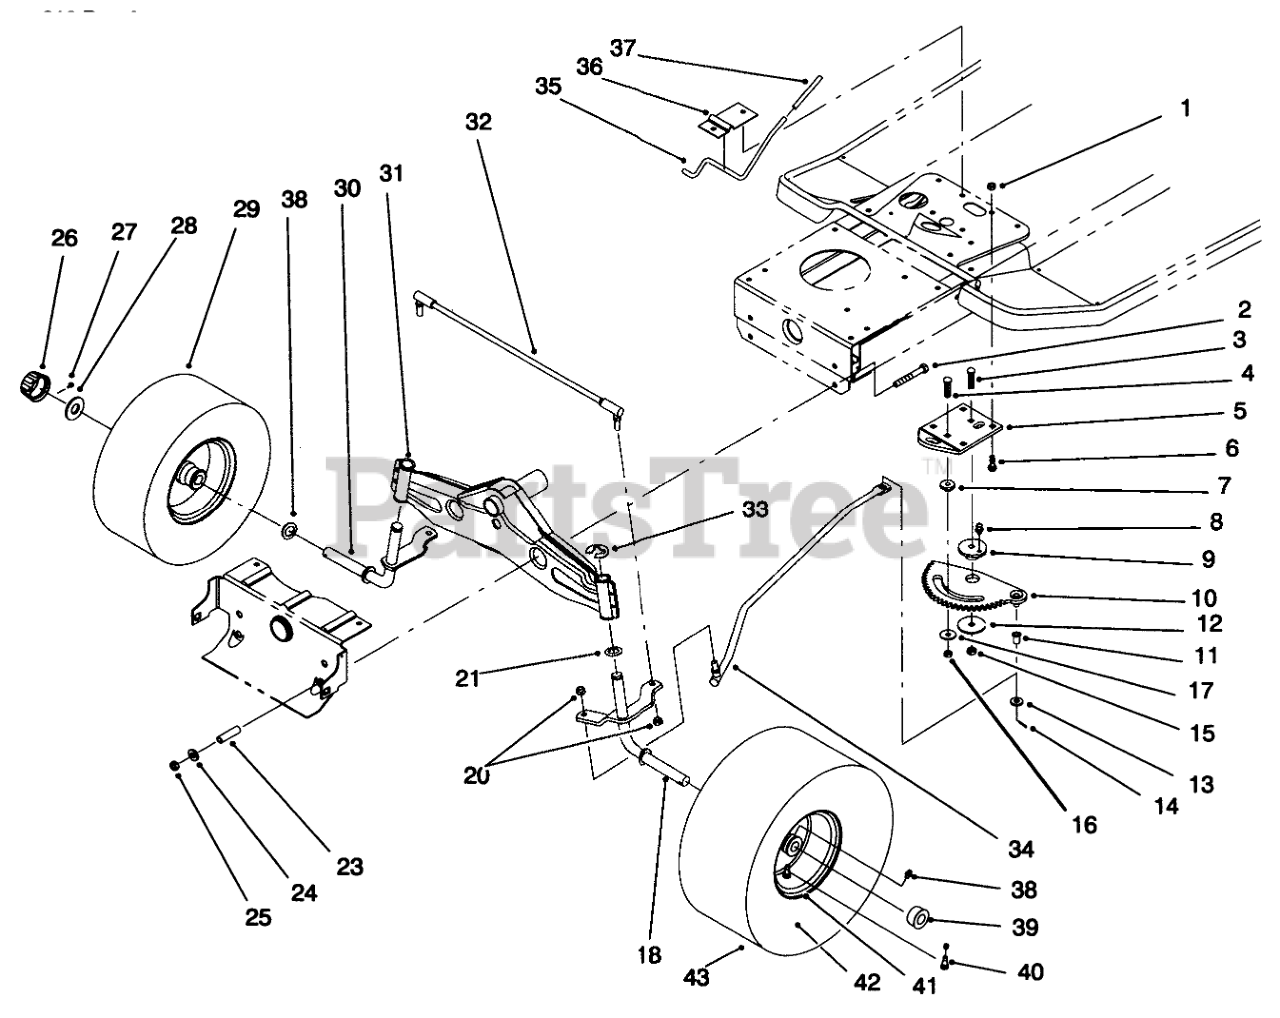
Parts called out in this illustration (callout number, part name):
1	NUT-LOCK, NI
2	SCREW-HH
3	SCREW-CARR
4	SCREW-CARR
5	Bracket-Steering Rack
6	BOLT-CARR
7	SPACER-RACK, STEERING
8	FITTING-GREASE
9	BUSHING-ECCENTRIC
10	RACK-STEERING
11	BUSHING-FLANGED, NYLON
12	WASHER-BEARING
13	WASHER-FLAT
14	PIN-COTTER
15	NUT-LOCK, NI
16	NUT-LOCK, NI
17	WASHER-PIVOT
18	Spindle-L.H.
20	NUT-HEX
21	WASHER-THRUST
23	SPACER
24	WASHER-FLAT
25	NUT-LOCK, NI
26	CAP-HUB
27	PIN-COTTER
28	WASHER-PLAIN
29:1	RIM ASM
29:2	TIRE 15 X 6.00 X 6
29:3	STEM-VALVE
29:4	BEARING-WHEEL
29:5	FITTING-GREASE
29:6	TUBE-INNER
30	Spindle-R.H.
31	Axle-Front
32	TIE ROD ASM
33	E-RING
34	LINK-DRAG
35	ROD-BRAKE, PARKING
36	Bracket-Parking Brake
37	GRIP-BRAKE, PARKING
38	WASHER-THRUST
